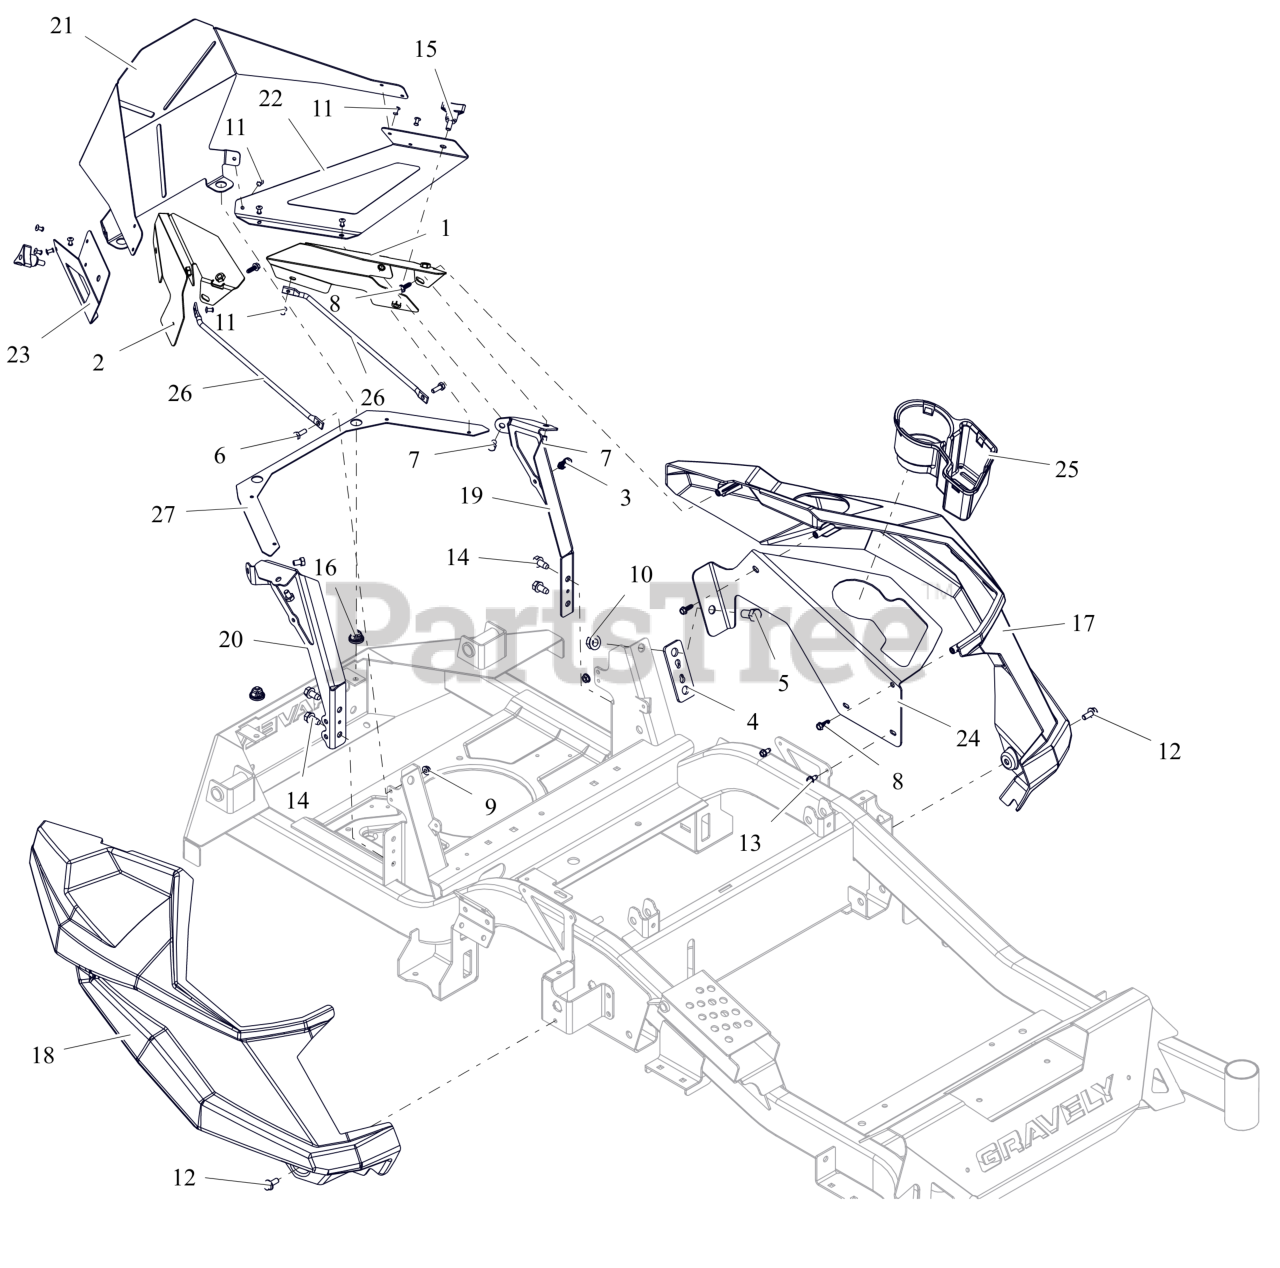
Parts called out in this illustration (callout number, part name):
1	PANEL, LH (RED)
2	PANEL, RH (RED)
3	CLIP, CABLE GUIDE
4	PLATE, CONTROL PANEL SPACER
5	BLT, HEX .50-13X1.00 G5 ZCC
6	BLT, HEX .25-20X.75 G5 ZCC
7	BLT, HEX .31-18X.50 GR5 ZCC
8	SCR, PLASTITE-HWH 0.25 X 0.75 ZC120
9	NUT-LK-CTR-FLG .25-20 ZC120
10	NUT-LK-TOP-FLG .500-13 GF ZCC
11	RIVET, #66 STEEL POP PD BLACK
12	BLT, SERHFWH 0.312-18X0.75 GR5 ZCC
13	SCR-TAP .25-20X.50 HWH ZCC
14	SCR,TAP .375-16X.75 HWH TR ZCC
15	KNOB,WING STUD 5/16-18 X .75
16	GROMMET, 10MM BOLLHOFF
17	FENDER, LH
18	FENDER, RH
19	BRKT, LH FENDER MTG (RED)
20	BRKT, RH FENDER MTG (RED)
21	WRAP, REAR (BLACK)
22	WRAP, REAR - LH (RED)
23	WRAP, REAR - RH (RED)
24	PANEL, HD CUPHOLDER (RED)
25	HOLDER, CUP
26	ROD, STIFFENER
27	STIFFENER, BACK WRAP (RED)
